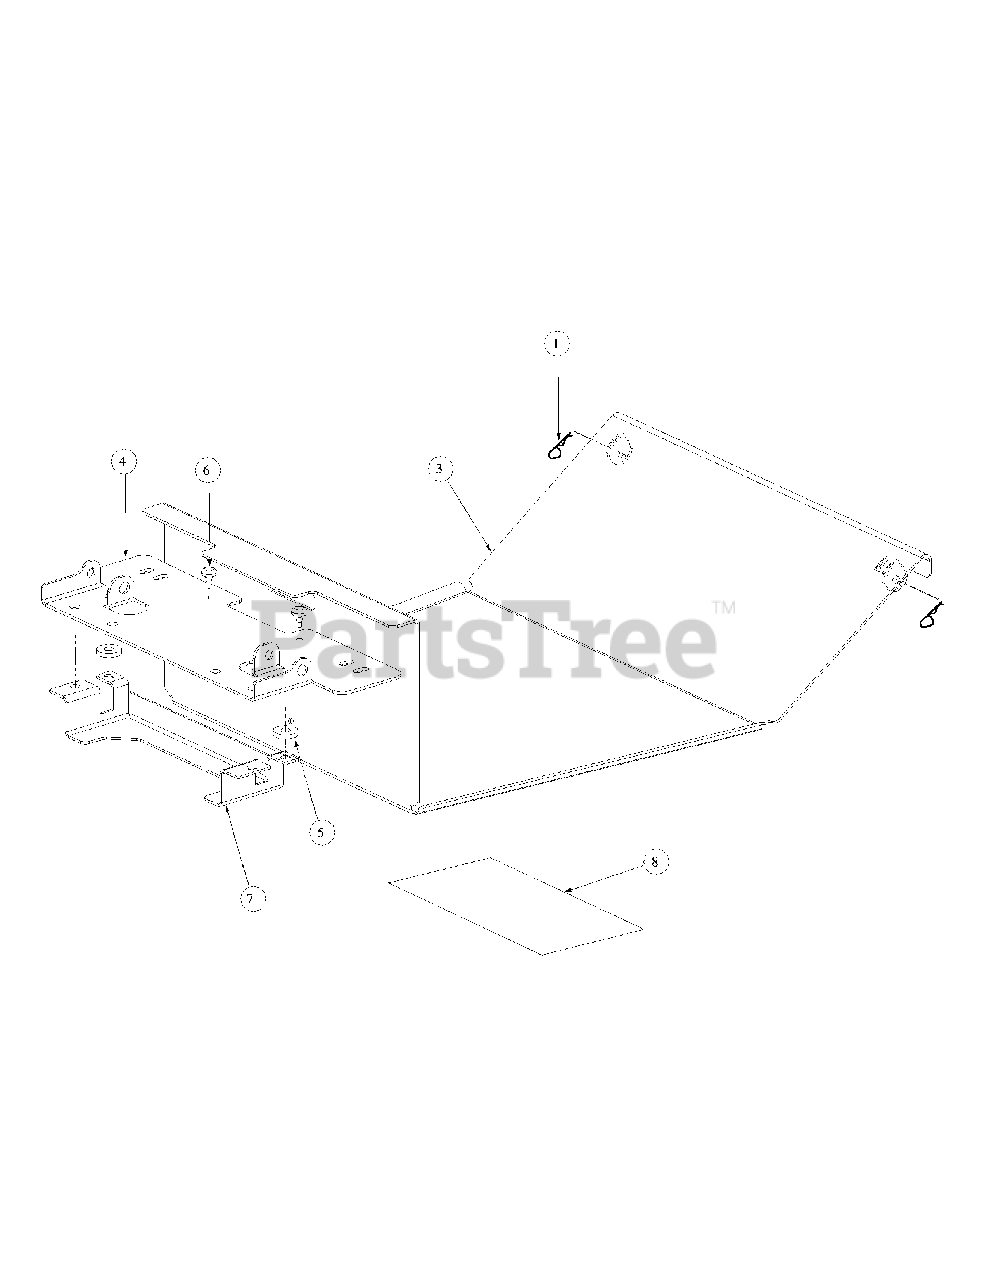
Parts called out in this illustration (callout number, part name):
1	Hair Pin, 3/8-1/2
3	Floor Panel Assembly
5	Washer
6	Rubber Bumper, .62 OD x .22 Thick
7	Support, Seat Bracket
8	Label, Belt Routing and Lubrication
